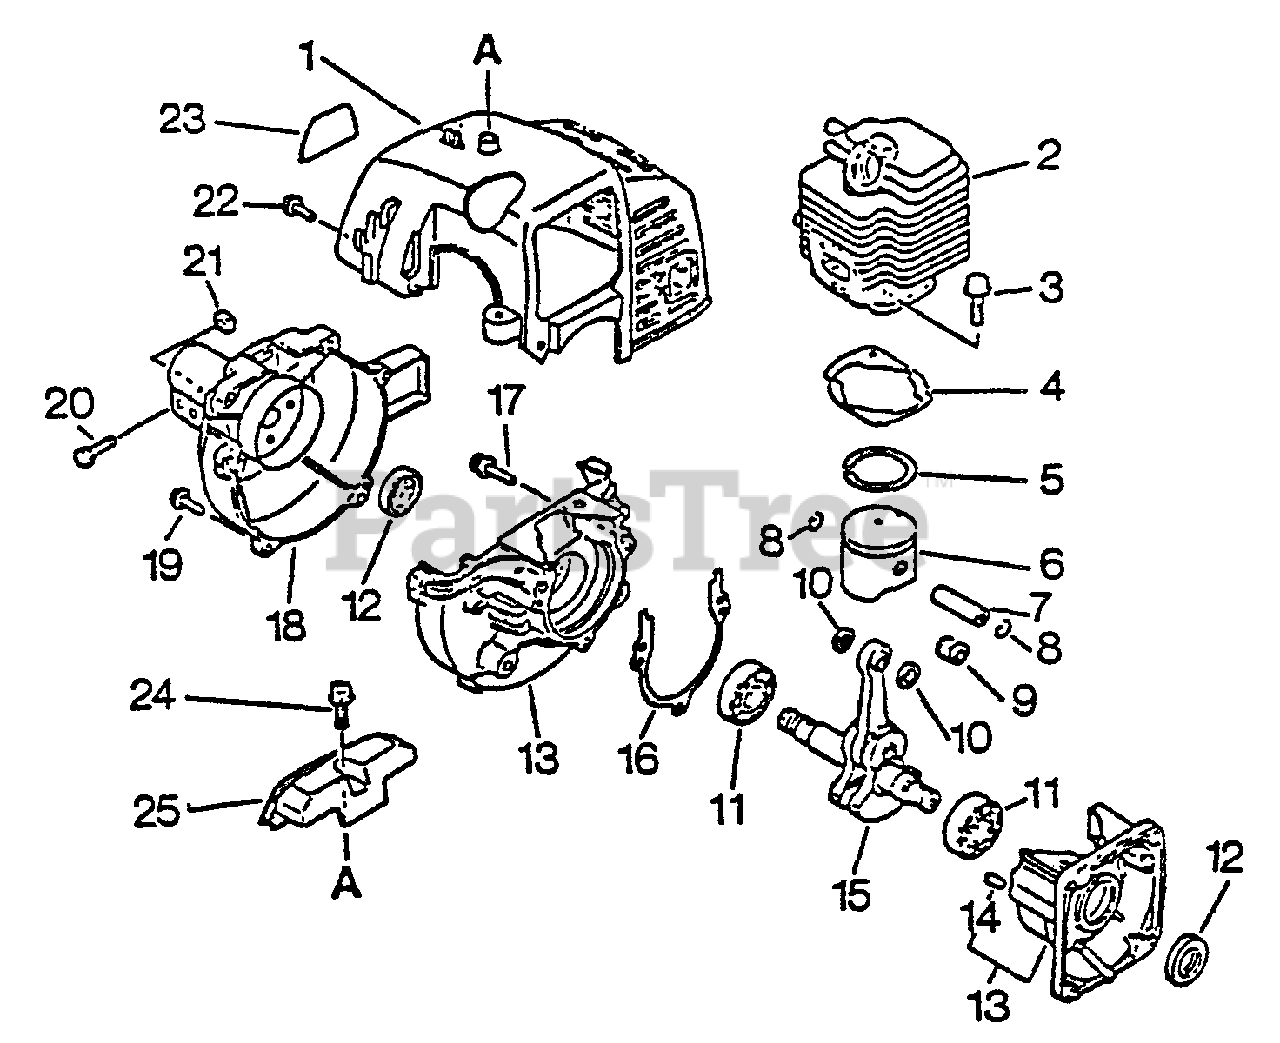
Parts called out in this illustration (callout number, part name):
1	COVER, ENGINE - GRAY
2	CYLINDER
3	BOLT 5×22
4	GASKET, CYLINDER
5	RING, PISTON
6	PISTON KIT
7	PIN, PISTON 8
8	RING, SNAP
9	BEARING, NEEDLE
10	WASHER, THRUST
11	BEARING, BALL - 6201 C3
12	SEAL, OIL 12
13	CRANKCASE KIT
14	PIN, LOCATING 4
15	CRANKSHAFT ASSY
16	GASKET, CRANKCASE
17	BOLT 5×28
18	FAN CASE ASSY
19	SCREW - 4×18
20	BOLT 5×28
21	NUT M5
22	SCREW 4×12
23	LABEL, MODEL
24	SCREW 5×16
25	GUARD, TOP - BLACK
